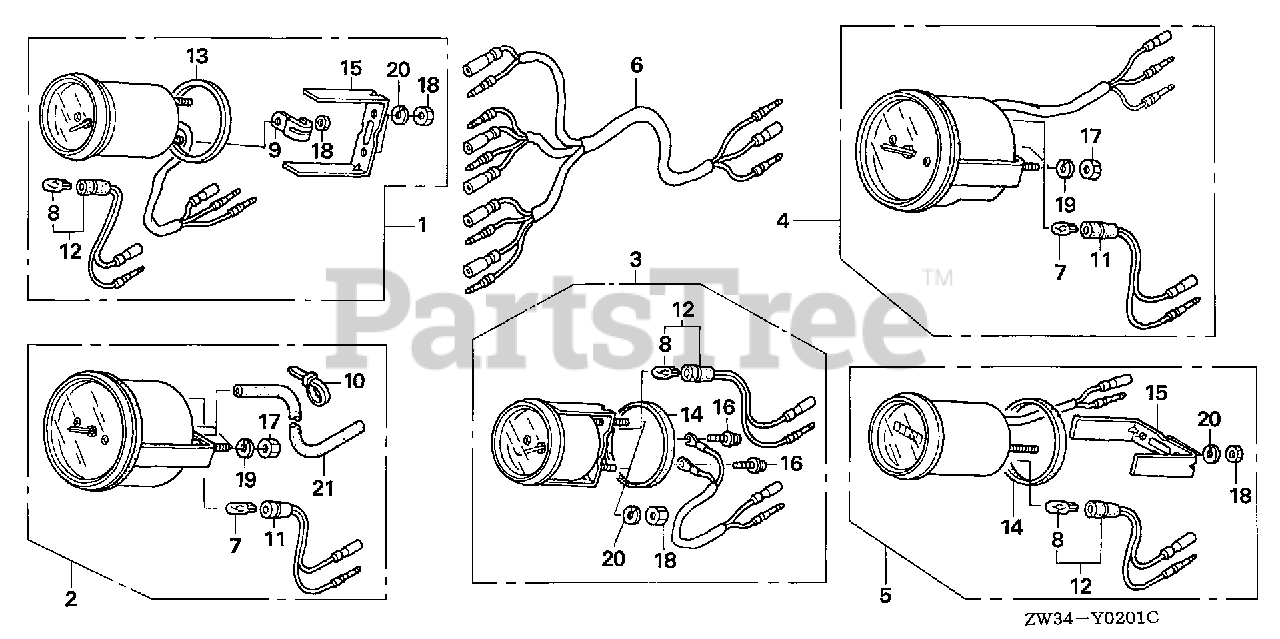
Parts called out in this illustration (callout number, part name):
1	METER KIT, TRIM (WHITE)
1	METER KIT, TRIM (B) (BLACK)
2	SPEEDOMETER KIT (WHITE)
2	SPEEDOMETER KIT *NHA85* (B) (BLACK)
3	METER KIT, VOLT (WHITE)
3	METER KIT, VOLT *NHA85* (B) (BLACK)
4	METER KIT, TACHO
4	METER KIT, TACHO (B)
5	METER KIT, HOUR (WHITE) (NA USE ALT:39700-ZW5-000ZA)
5	METER KIT, HOUR (B) (NA USE ALT:39700-ZW5-000ZA)
6	HARNESS ASSY., METER (B)
7	BULB, WEDGE BASE (T10) (12V 1.7W) (STANLEY)
8	BULB, WEDGE BASE (12V1.7W) (TOSHIBA)
9	CLAMP
10	BAND, SELF-LOCK
11	SOCKET
12	SOCKET
13	GASKET (TO 1015209) (FROM 1015210)
14	GASKET
15	BRACKET (TO 1015209) (FROM 1015210)
16	SCREW-WASHER (3X22)
17	NUT, HEX. (5MM)
18	NUT, HEX. (4MM)
19	WASHER, SPRING (5MM)
20	WASHER, SPRING (4MM)
21	TUBE, SPEED METER (4X7X8000)
